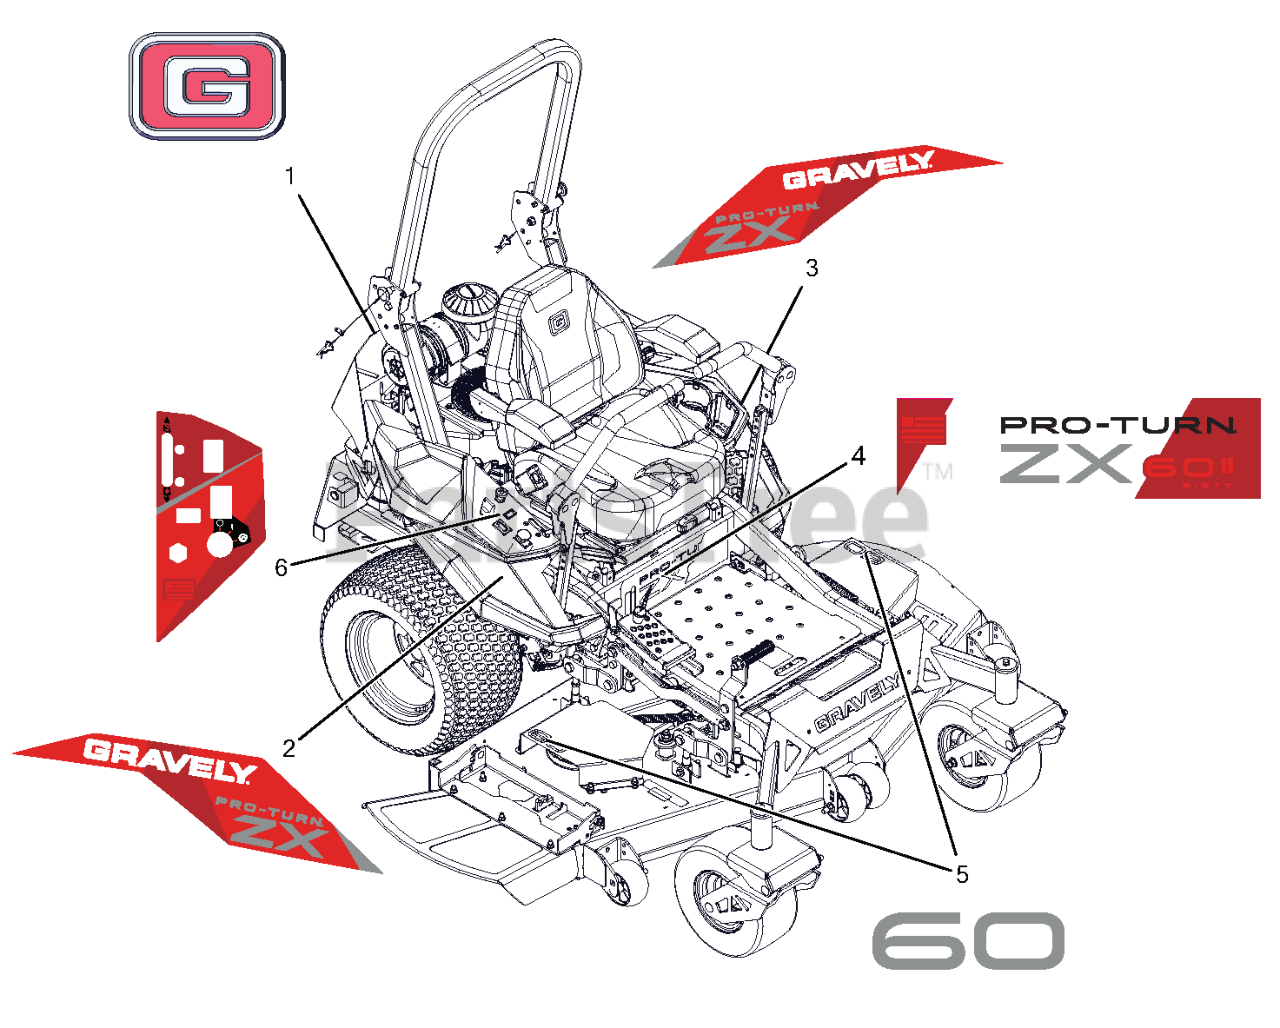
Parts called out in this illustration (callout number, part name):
1	DECAL, GRAVELY BRAND
2	DECAL, FENDER RH - PTZX
3	DECAL, FENDER LH - PTZX
4	DECAL, PTZX - 60
5	DECAL, DECK - 60
6	DECAL, CONTROL PANEL
